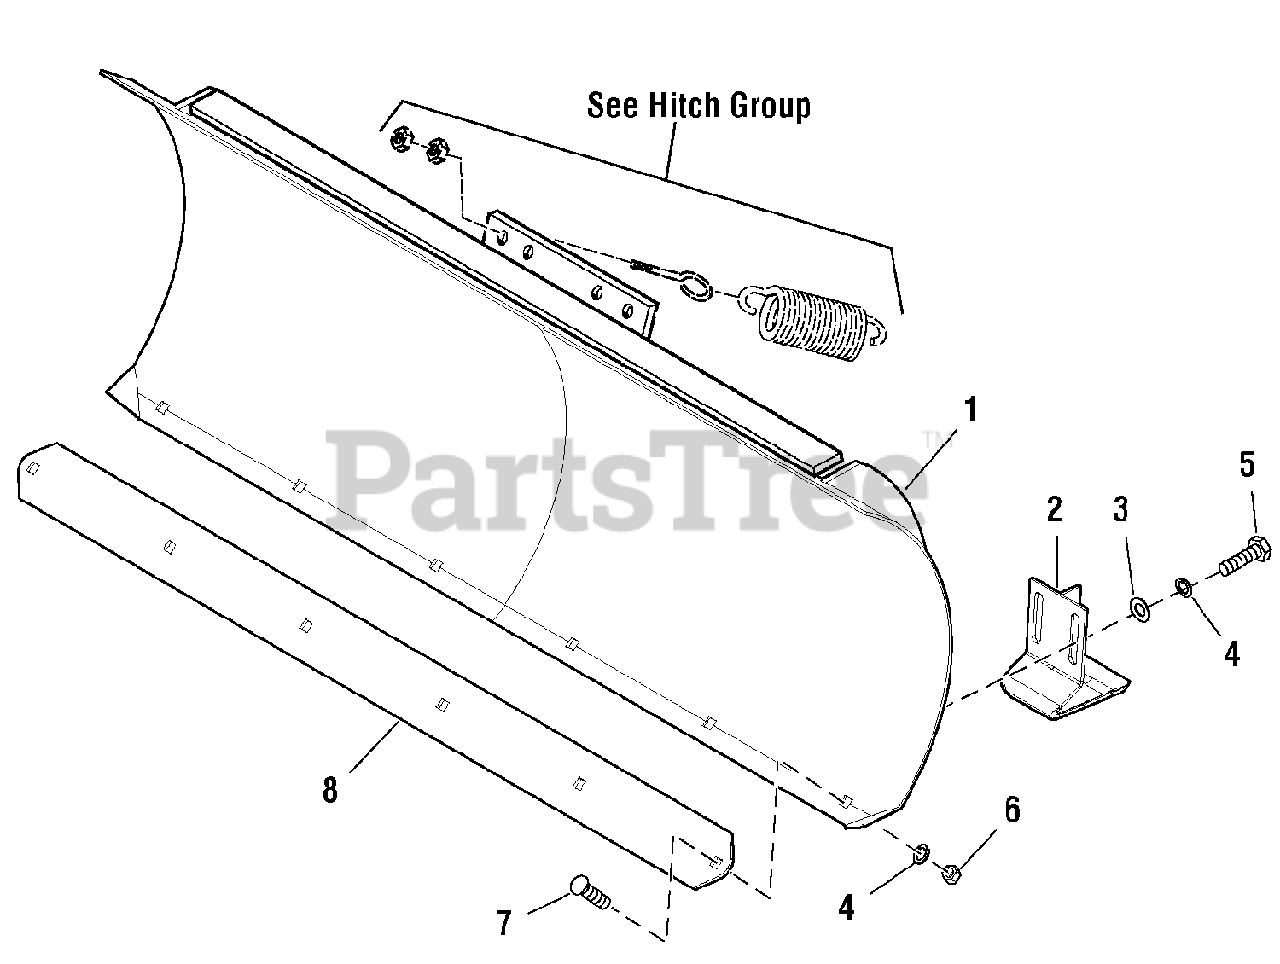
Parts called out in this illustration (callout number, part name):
1	BLADE ASSEMBLY
2	SHOE ASSEMBLY
3	WASHER, 3/8
4	LOCKWASHER, 3/8
5	CAPSCREW, Hex Head, 3/8-16 x 3/4
6	NUT, Hex, 3/8-16
7	CARRIAGE BOLT, 3/8-16 x 1
8	PLATE, Wear
